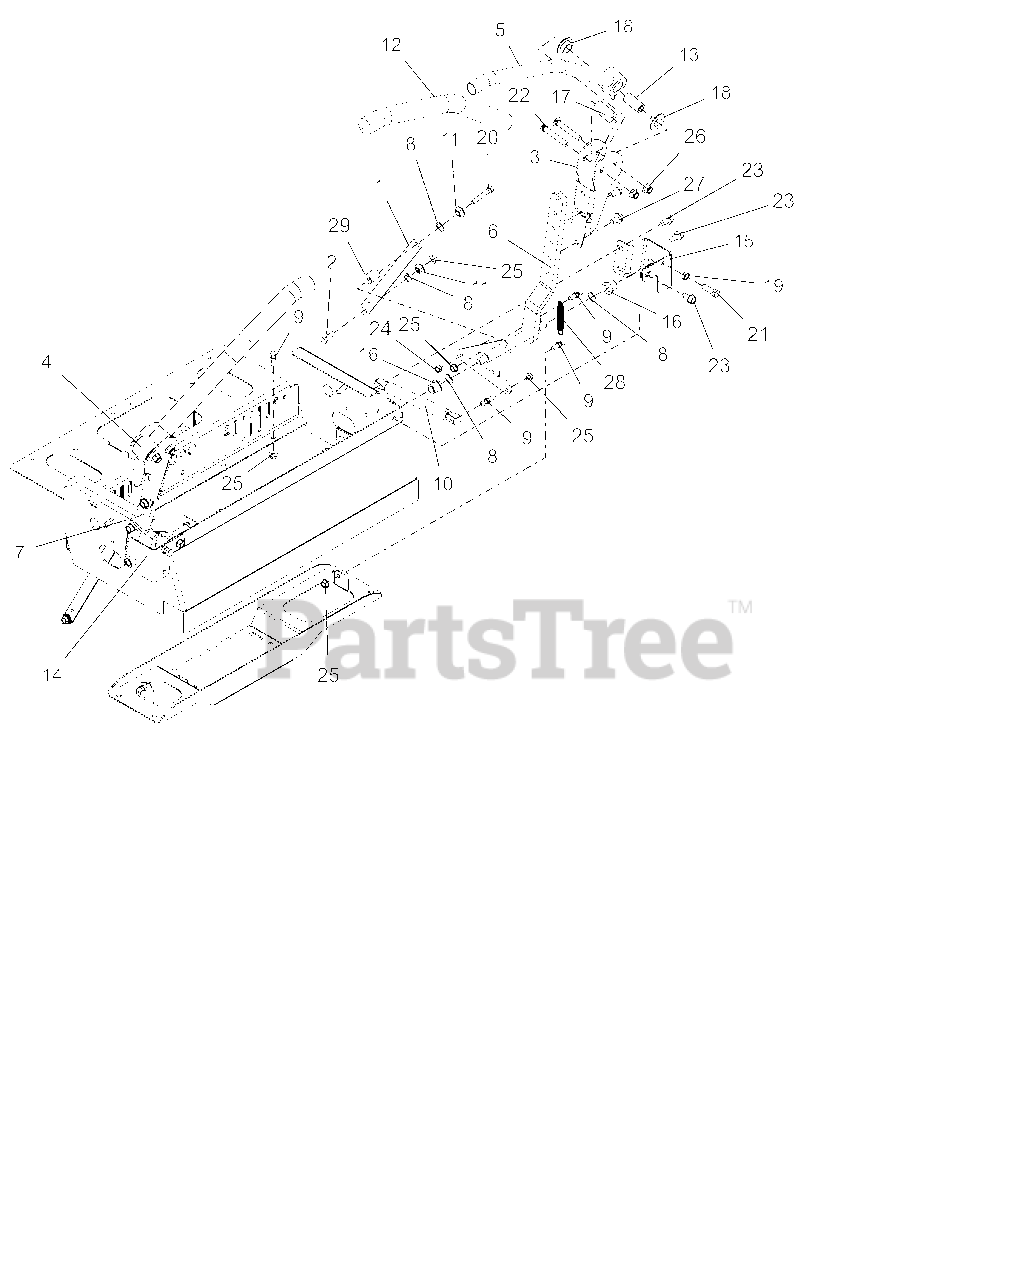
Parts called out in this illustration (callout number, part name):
1	LINK, STEERING CONTROL
2	@BLT-HEX .31-18X1.00 GR5 YWZC
3	ADJ UPPER CONTROL ARM BRKT-BLK
4	WLDMT, CONTROL HANDLE- BLK
5	WLDMT, CONTROL HANDLE- BLK
6	WLDMT, LH LOWER CONTROL ARM
7	WLDMT, RH LOWER CONTROL ARM
8	WAVE WASHER .531X.781X.125FH
9	STUD- BALL
10	DAMPER
11	BSHG-FLG .32X.500X.344X.880
12	GRIP, HANDLEBAR
13	SPACER, STEERING ARM
14	PT200/400 RH CNTRL STP BRK-RED
15	PT200/400 LH CNTRL STP BRK-RED
16	BHSG-FLG .500X.750X.750X.125
17	BSHG, ECCENTRIC.406X.875X1.625
18	BSHG-FLG .762X1.48X.44 NYL
19	NUT-HEX-JAM .375-16 YWZC
20	@BLT-HEX .31-18X2.00 GR5 YWZC
21	@BLT-HEX .38-16X1.25 GR5 YWZC
22	BLT-RDHDSQSHK, 38-16X2.50 G5YZ
23	@SCR-TAP .38-16X.75 HWH TR YWZ
24	@NUT-LK-CTR .31-18 YWZC
25	@NUT-LK-TOP-FLG .31-18 YWZC
26	@NUT-LK-NYL-FLG .38-16 YWZC
27	BLT, SCRHFWH .375-16X.625 YWZC
28	SPRING,EXT,.061X.50X3.0
29	ECCENTRIC
